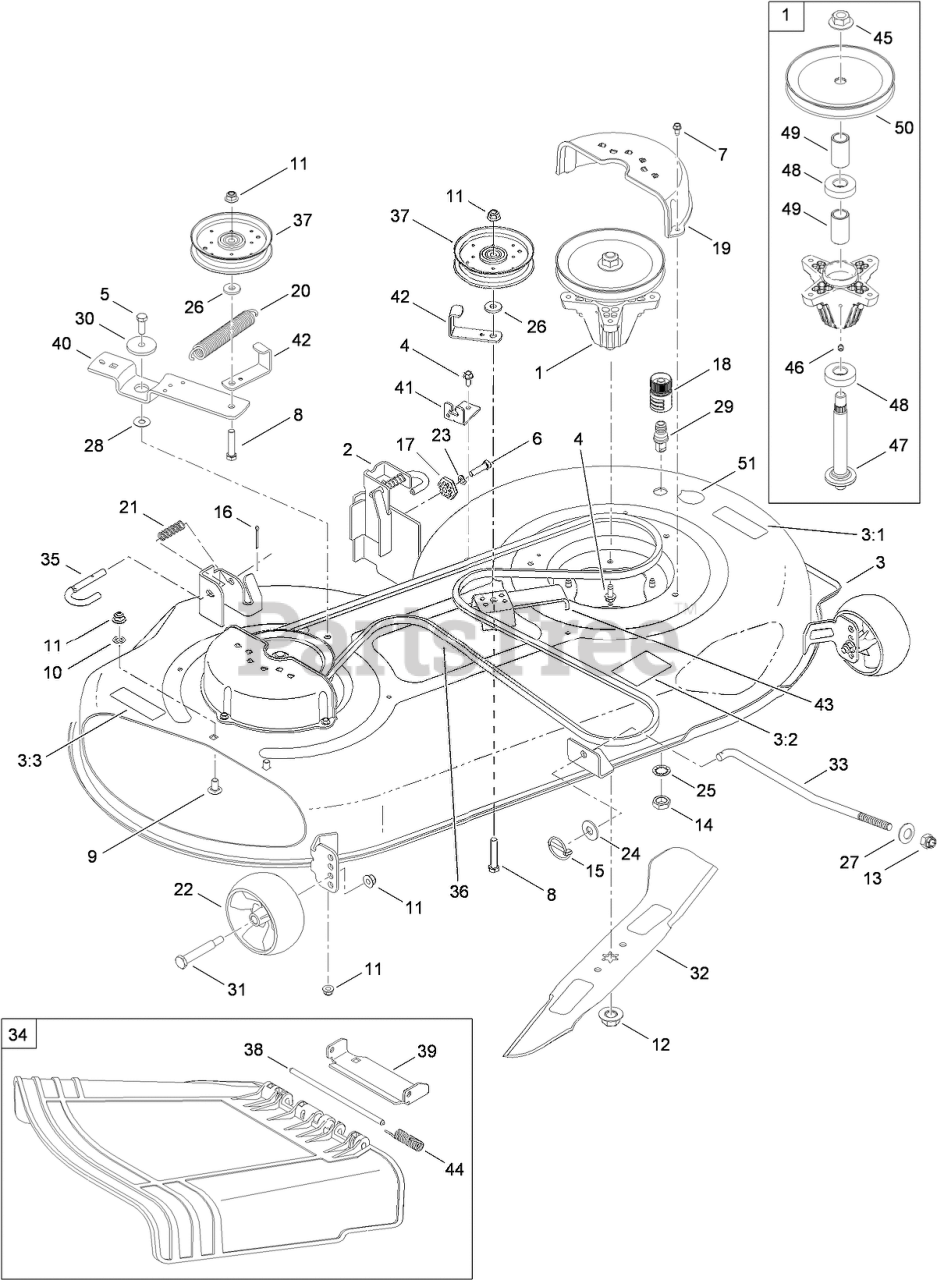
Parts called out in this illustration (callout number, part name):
1	SPINDLE ASM
2	LH HANGER BRACKET ASM
3	46 INCH DECK ASM
3:1	DECAL-DECK
3:2	DECAL-BELT ROUTING
3:3	DECAL-CHUTE
4	SCREW-TAP
5	SCREW-HH
6	SCREW-HH
7	SCREW-HWHTF
8	SCREW-HH
9	BOLT-CARR
10	NUT-PUSH
11	NUT-LOCK, FLANGE
12	NUT-LOCK, FLANGE
14	NUT-HEX
15	PIN-LYNCH
16	PIN-COTTER
17	GEAR-ADJUSTMENT, DECK
18	ADAPTER-NOZZLE, WATER
19	COVER-BELT, UNIVERSAL
20	SPRING-EXTENSION
21	SPRING-COMPRESSION
22	WHEEL-DECK, FRONT
23	WASHER-LOCK
24	WASHER-FLAT
25	WASHER-LOCK
26	Washer-Flat
27	WASHER-BELLVILLE
28	WASHER-FLAT
29	NOZZLE-WATER, DECK
30	SPACER-SHOULDER
31	BOLT-SHOULDER
32	BLADE-2-IN-1
33	ROD-LIFT, DECK
34	CHUTE ASM
35	PIN-HANDLE, DECK RELEASE
36	BELT-V
37	PULLEY-IDLER
38	PIN-HINGE
39	BRACKET-CHUTE
40	BRACKET-PIVOT, IDLER
41	BRACKET-CABLE, DECK ENGAGE
42	BRACKET-GUARD, BELT
43	BRACKET-SUPPORT, IDLER
44	SPRING-TORSION
45	NUT-LOCK, FLANGE
46	FITTING-GREASE
47	SHAFT-SPINDLE
48	BEARING-BALL
49	SPACER
50	PULLEY-DECK
51	DECAL-DECK WASH SYSTEM
